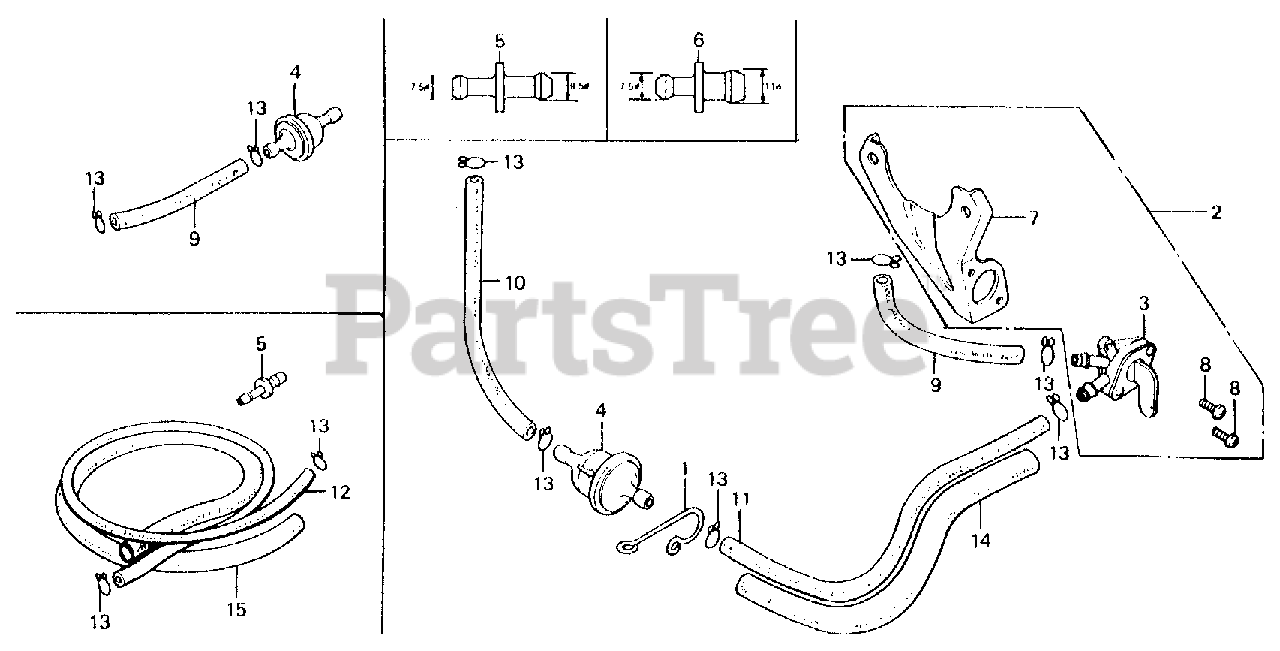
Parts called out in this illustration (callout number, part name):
4	FILTER, FUEL (NOT AVAILABLE)
5	JOINT, FUEL TUBE
6	JOINT, FUEL TUBE
9	BULK HOSE, FUEL (5.5X8000) (5.5X100)
12	BULK HOSE, FUEL (5.5X8000) (5.5X360)
13	CLIP, TUBE (B10)
15	BULK HOSE, VACUUM (11X1000) (11X300)
